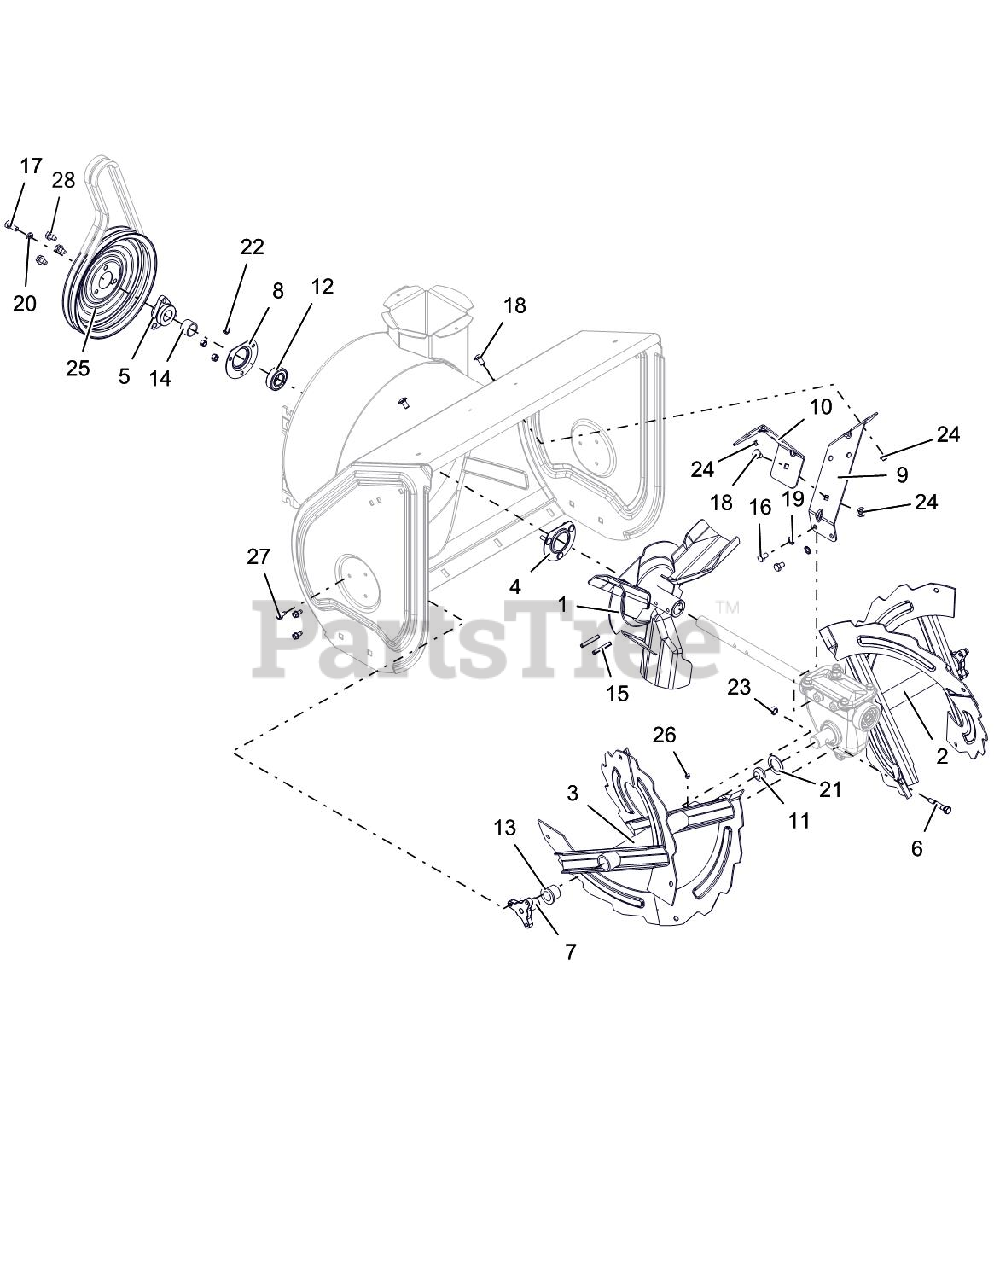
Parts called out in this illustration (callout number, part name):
1	IMPELLER, 3 BLADE-14"
2	RAKE, LH W/ZERK - 24"
3	RAKE, RH W/ZERK - 24"
4	BEARING FLANGE
5	PULLEY HUB, D-BORE .87 DELUXE
6	SHEAR BOLT SERVICE ASSEMBLY
7	SUPPORT, RAKE BUSHING
8	BEARING FLANGE
9	BRACKET, GEARCASE SUPPORT - LH
10	BRACKET, GEARCASE SUPPORT - RH
11	PLUG, RAKE TUBE
12	BRG-BALL .876 X 1.750 X .50
13	BSHG-FLG, NY.778 ID X 1.018 OD
14	BSHG,SPCR .895X1.065X.693
15	PIN-ROLL .250X1.75
16	@BLT-HEX .31-18X.50 GR5 YWZC
17	BLT-HEX .31-24X.75 YWZC GR5
18	BLT-RDHDSQSHNK.31-18X.62 YZ-LK
19	@WSHR-LK-EXT.326X.599X.031YWZC
20	WSHR-LK .312X.097 HVY YWZC
21	WSHR-FL-STL 1.010X1.505X.062YZ
22	@NUT-LK-CTR .25-20 YWZC
23	@NUT-LK-CTR .31-18 YWZC
24	@NUT-LK-TOP-FLG .31-18 YWZC
25	PULLEY, SPIN FORM DUAL GROOVE
26	ZERK,FITTING .25X.125 DRIVE IN
27	SCR-TAP .25-20X.50 HWH TR YWZ
28	@SCR-TAP .31-18X.50 HWH TR YWZ
